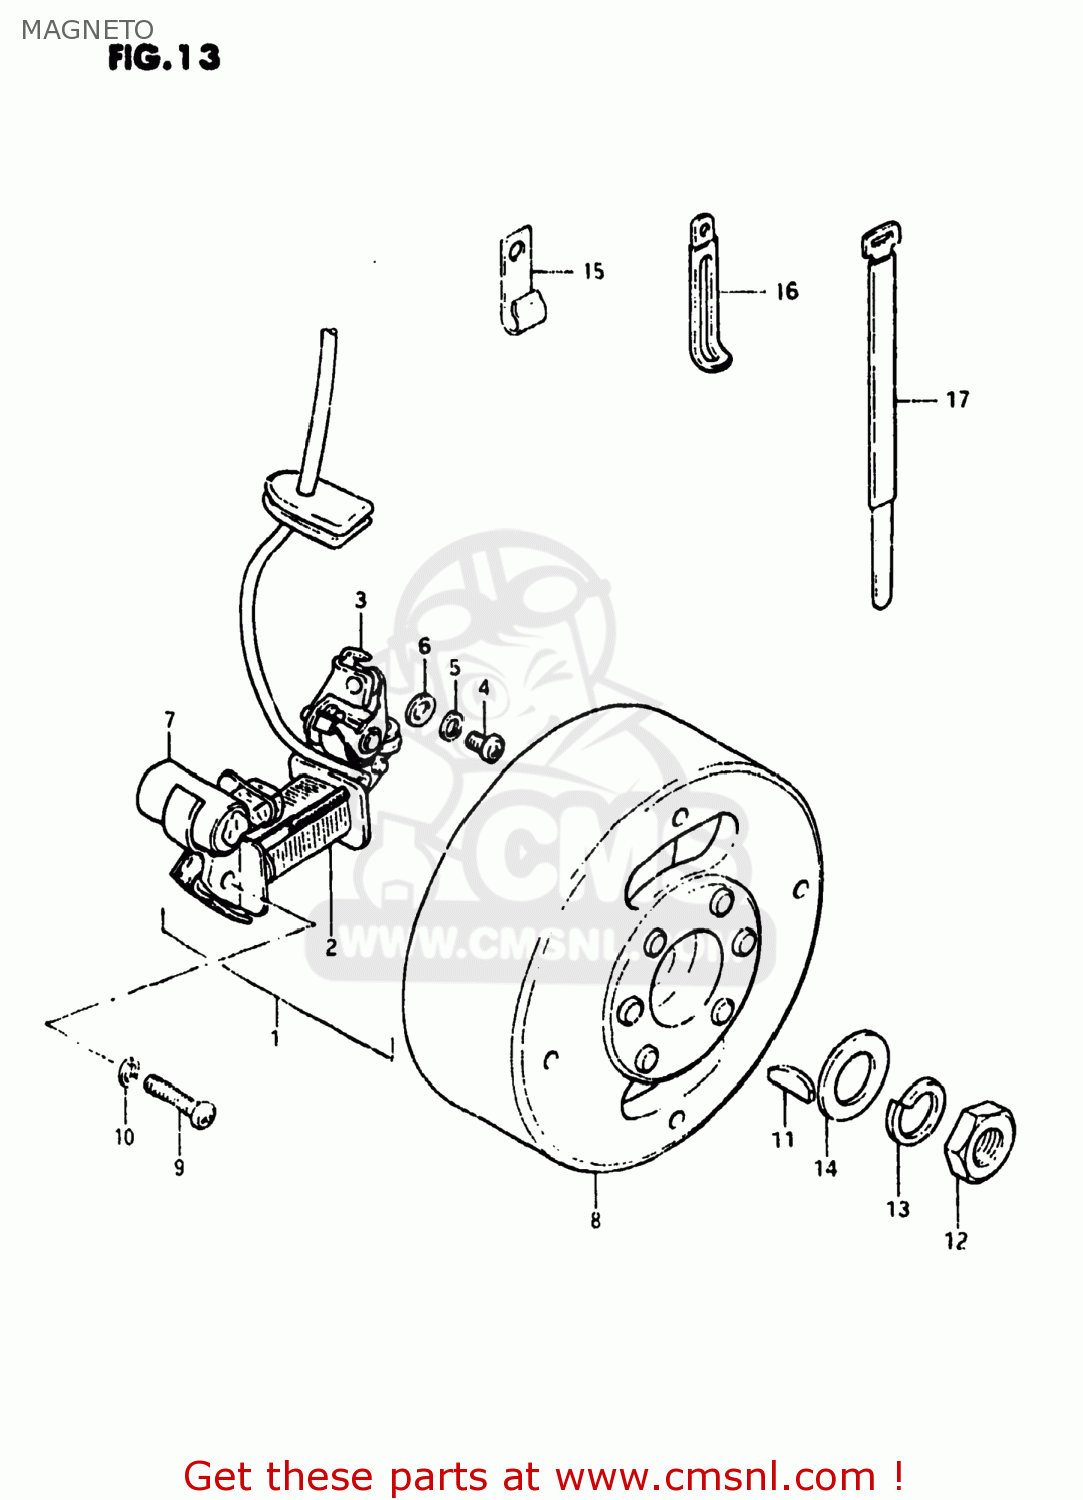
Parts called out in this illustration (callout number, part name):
1	STATOR ASSEMBLY
2	COIL ASSY,IGNITION PRIMARY
3	POINT ASSY,CONTACT
4	SCREW(4X10)
5	LOCK WASHER
6	WASHER
7	CONDENSER,MAGNETO
8	ROTOR ASSEMBLY
9	SCREW 4X25
10	LOCK WASHER
11	KEY
12	NUT (10MM)
13	LOCK WASHER
14	WASHER
15	CLAMP
16	CLAMP L:35
17	CLAMP
